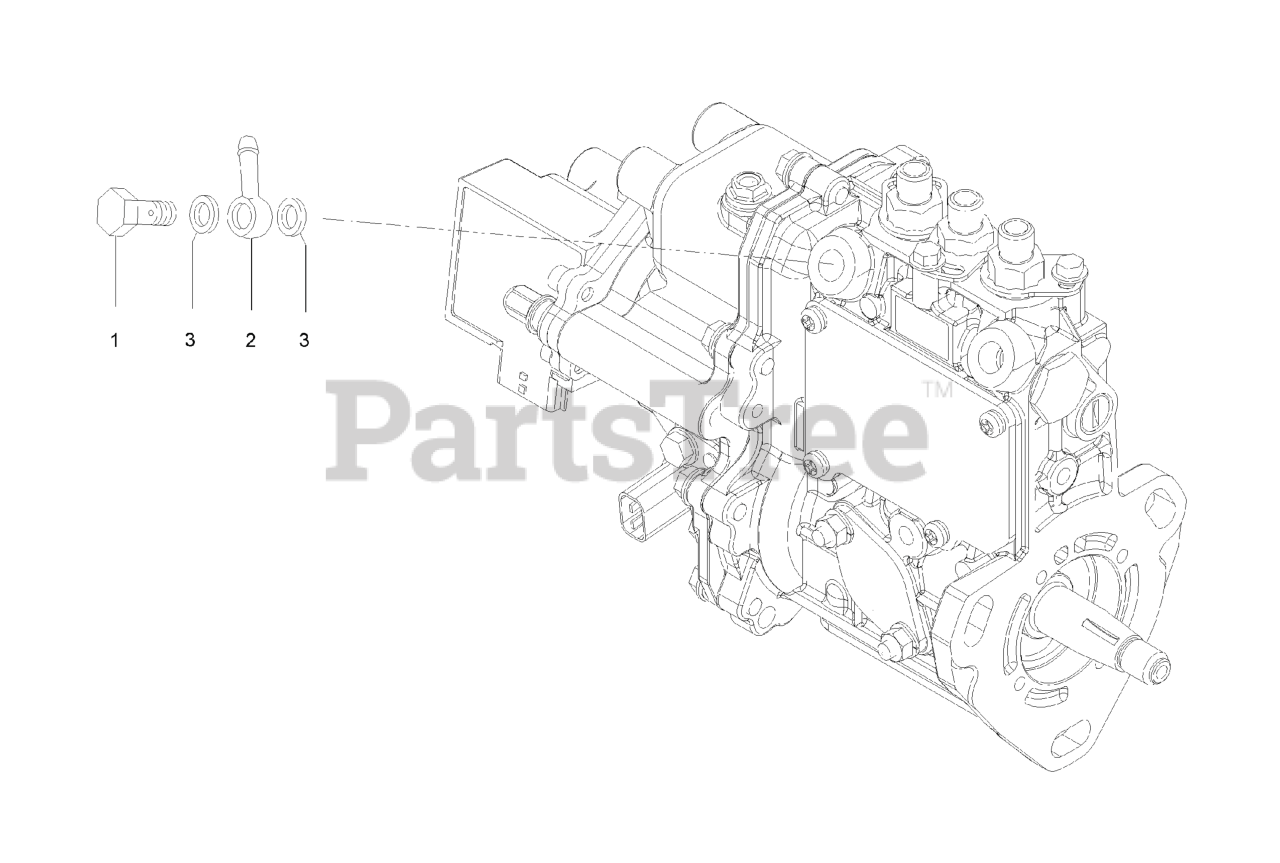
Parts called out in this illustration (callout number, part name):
1	BOLT-PIPE JOINT
2	JOINT-PIPE
3	WASHER-SEAL
